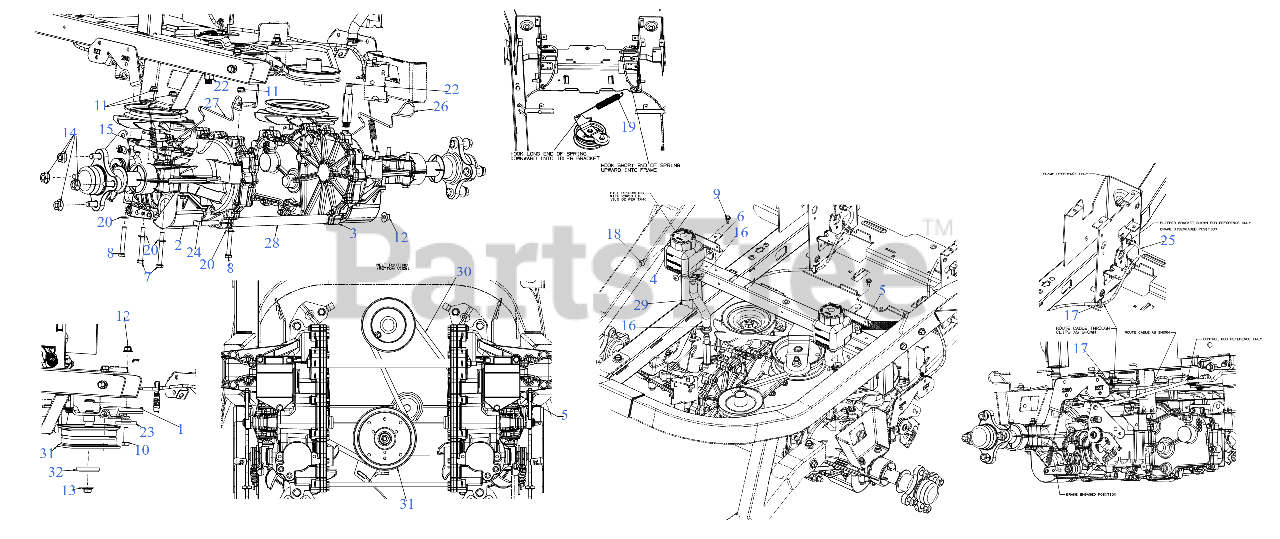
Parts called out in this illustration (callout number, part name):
1	DRIVE IDLER BRACKET ASSEMBLY
2	HYDRO TRANSMISSION (LH)
3	HYDRO TRANSMISSION (RH)
4	EXPANSION TANK
4	CAP-EXPANSION TANK
5	EXPANSION TANK BRACKET (RH)
6	EXPANSION TANK BRACKET (LH)
7	HEX SCREW 5/16-18 x 2.75
8	HEX SCREW 5/16-18 x 2.25 GR5
9	SCREW M6-1 x .625
10	SCREW 3/8-16 x 1.25 GR5
11	FLANGE LOCK NUT 5/16-18
13	FLANGE LOCK NUT
14	HEX FLANGE NUT 7/16-14
15	BOW TIE COTTER PIN 1/4-5/16
16	FUEL HOSE CLAMP .75
17	CABLE RETAINER CLIP
18	POP RIVET - .188 DIAMETER
19	EXTENSION SPRING .75 DIA X 10.27
20	FLAT WASHER
22	EXTENSION FITTING 9/16-18
23	SHOULDER SPACER
24	SUPPORT TUBE ROD
25	PARK BRAKE CABLE
26	HYDRO BYPASS ROD (RH)
27	HYDRO BYPASS ROD (LH)
28	SUPPORT TUBE
29	EXPANSION TANK HOSE
30	BELT-TRANS DRIVE A x 69.1
30	Cub Cadet DRIVE BELT (-05874)
31	IDLER PULLEY 4.50" DIA
32	IDLER PULLEY CAP
